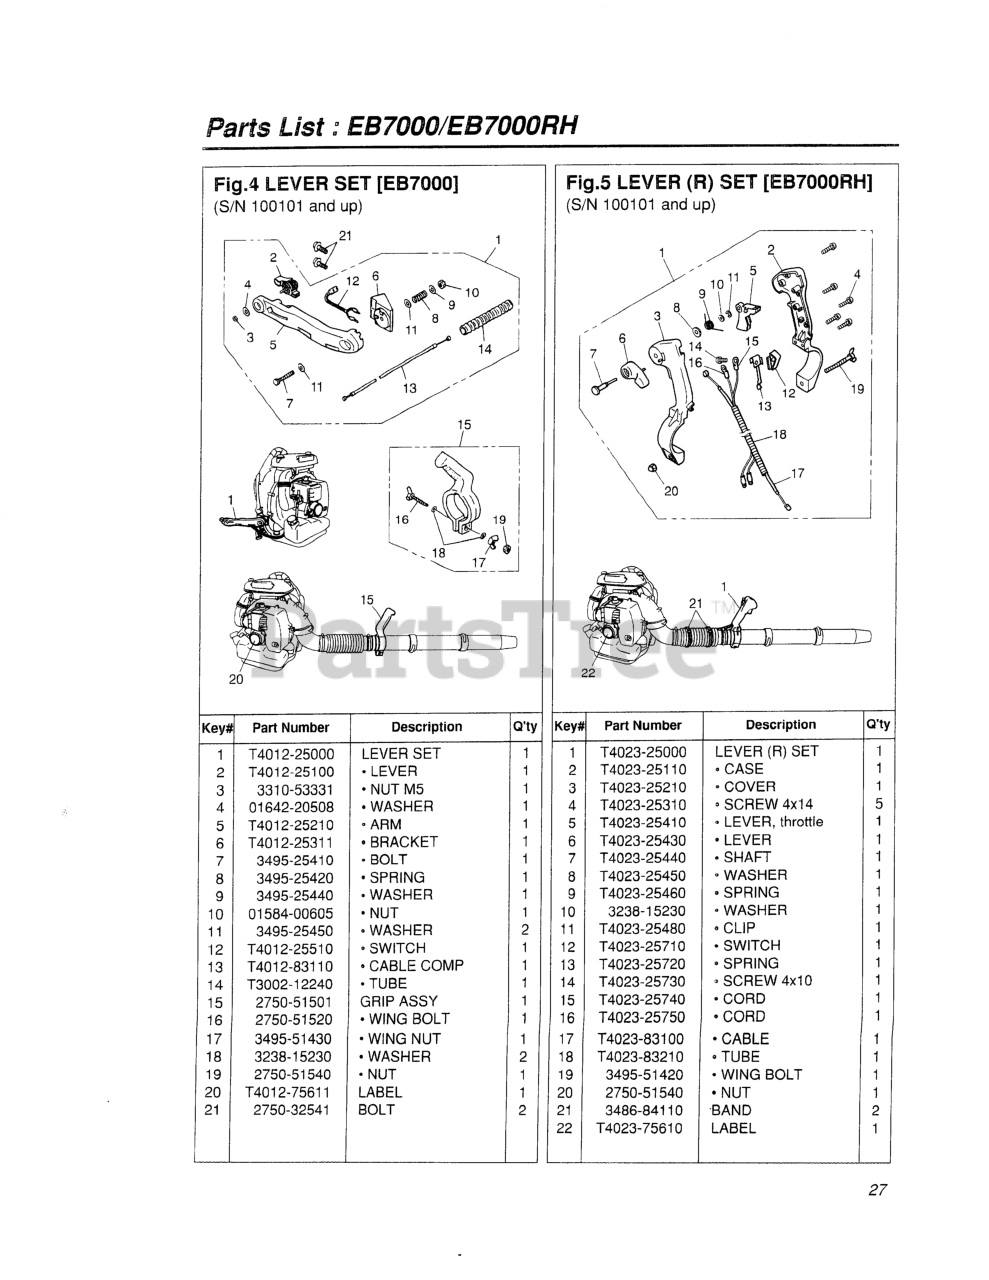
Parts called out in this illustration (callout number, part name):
4	SCREW 4X14
5	LEVER, THROTTLE
7	SHAFT
8	WASHER
9	SPRING WASHER
10	WASHER
11	CLIP
12	SWITCH
13	SPRING
14	SCREW 4X10
15	CORD
16	CORD
17	CABLE
19	BOLT, WING
20	NUT
21	BAND
22	RECOIL LABEL, EB7000RH
